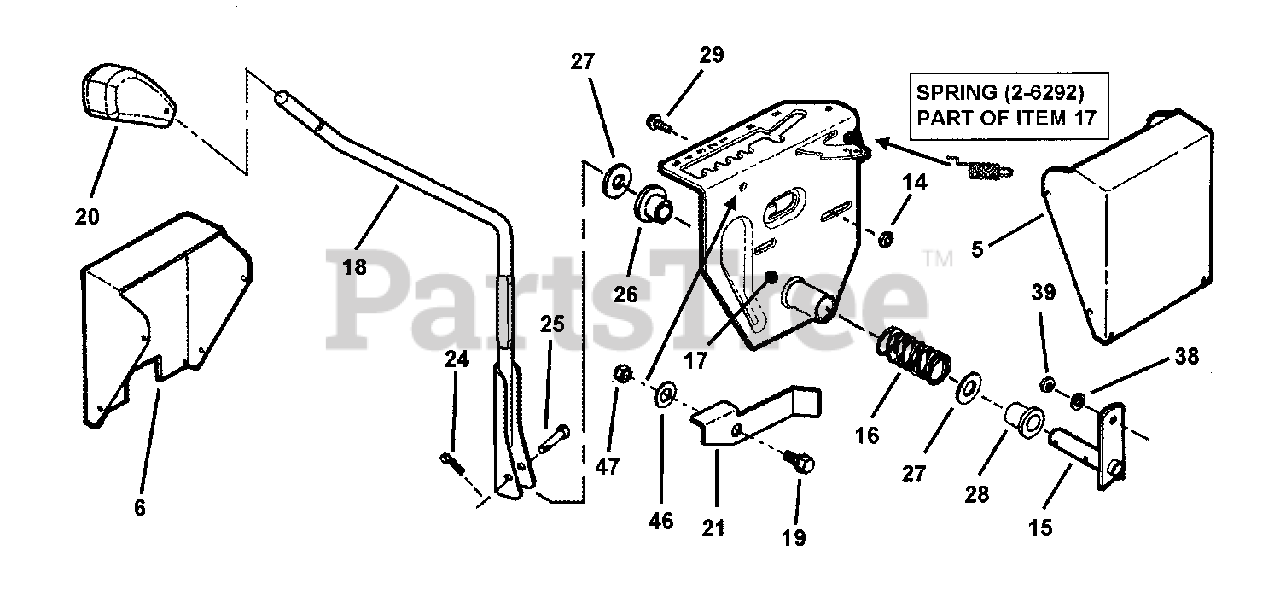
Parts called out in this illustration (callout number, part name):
5	COVER, Battery
6	COVER, Solenoid (Kohler)
14	NUT, 5/16-18 Hex, GR 5 or B
15	ARM, Shift Handle (weldment)
16	SPRING, Shift Detent
17	ASSEMBLY, Speed Adjustment Latch
18	HANDLE, Shift (weldment)
19	SHOULDER BOLT, 5/16-18
20	GRIP, Shift Handle
21	LEVER, Over-Ride
24	COTTER PIN, 3/32 x 3/4"
25	PIN, 1/4 x 1-3/4" Tapered Clevis
26	BUSHING, 3/4 x 1.62 Flange (Nylon)
27	WASHER, Thrust
28	BUSHING, 3/4 x I.O. Flange (Nylon)
29	SCREW, 5/16-18 x 5/8" Hex Washer Self-Tap
38	WASHER, .32 x .58 x .08 Split Lock
39	NUT, 5/16-24 Hex, GR5
46	WASHER, .47 x .92 x .065 Flat
47	NUT, 5/16-18 Hex Nyloc
